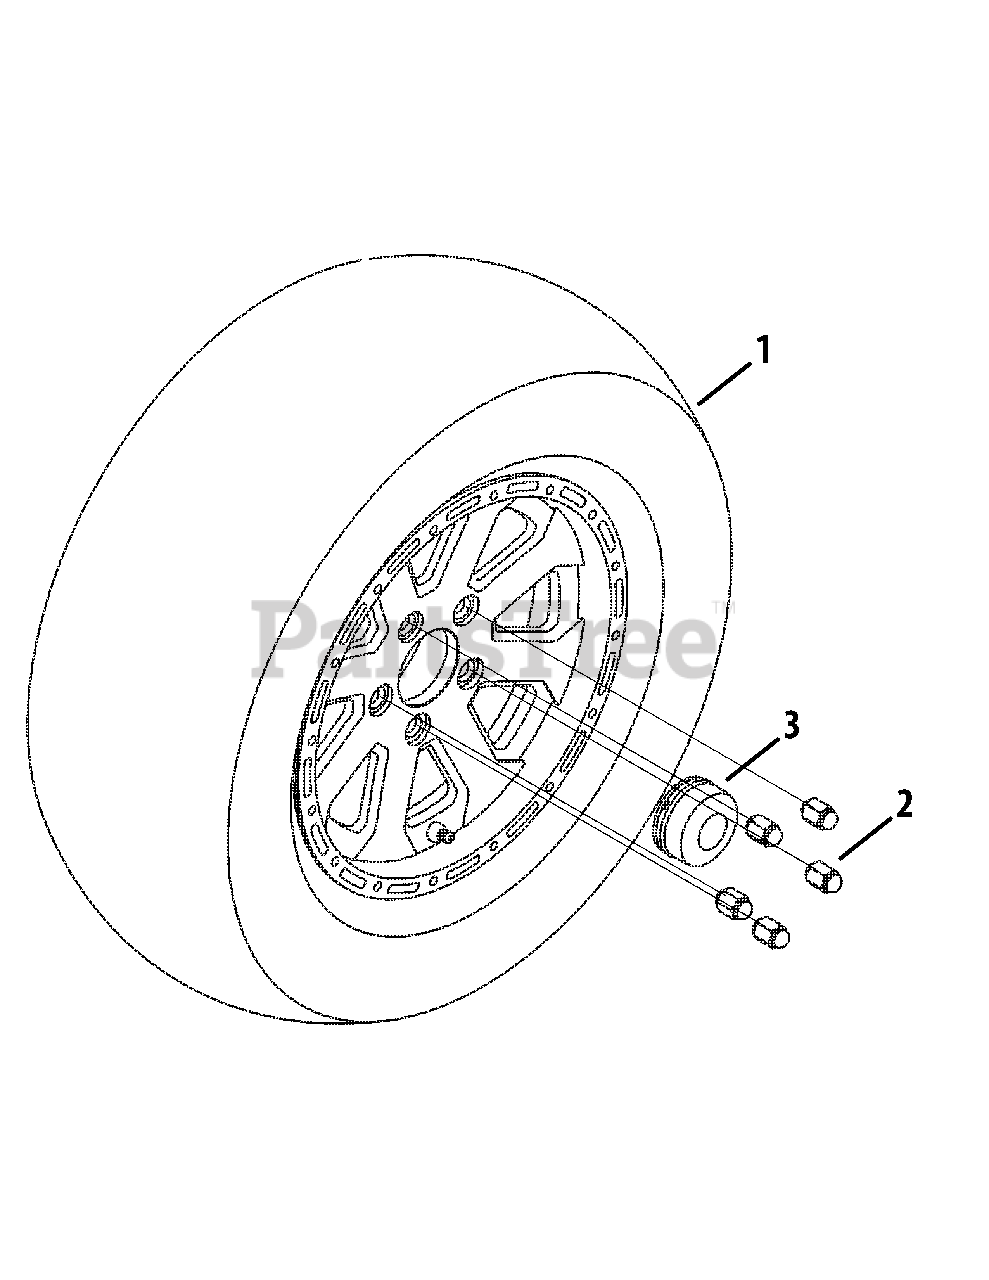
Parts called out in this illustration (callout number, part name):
1	Rim Only, 14 x 8, Rear
1	Tire Only, 26 x 11-14, Rear
1	Rim Only, 14 x 7, Front
1	Tire Only, 26 x 9-14, Front
2	Nut, Lug, 7/16-14
3	Cap, Wheel
